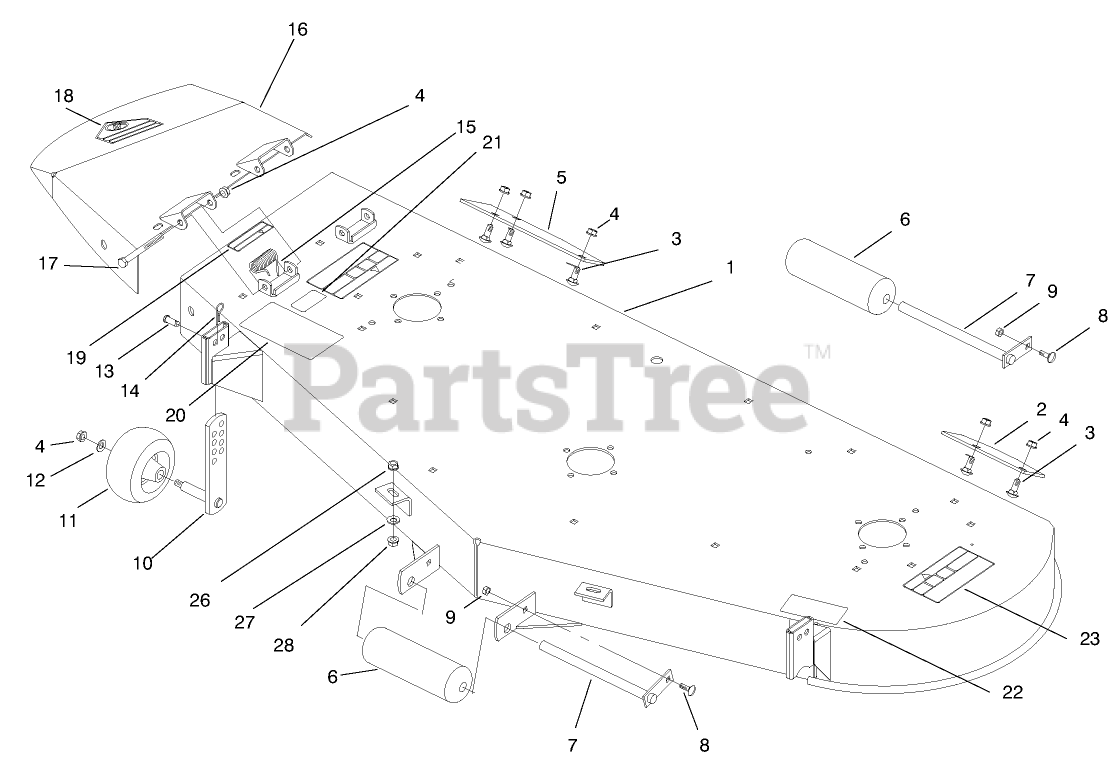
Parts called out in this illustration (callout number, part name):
1	Deck & Decal Asm
2	PLATE-WEAR, LH
3	BOLT-CARR
4	NUT-LOCK, NI
5	PLAT-WER RH
6	ROLLER-ANTI SCALP
8	BOLT-CARR
9	NUT-LOCK, NI
10	GAGE-WHEEL
11	WHEEL-GAGE
12	WASHER-FLAT
13	PIN-CLEVIS 3/8 X 1
14	PIN-HAIR
15	SPRING
16	Chute & Decal ASM
17	SCREW-HH
18	DECAL-DANGER
19	DECAL-DANGER
20	DECAL BELT INSTALLATION
21	DECAL - SAFETY
22	DECAL - WHEEL ADJUSTMENT
23	DECAL-DANGER, THROWN OBJECT
26	NUT-LOCK, NI
27	WASHER-FLAT
28	NUT-FLANGE
